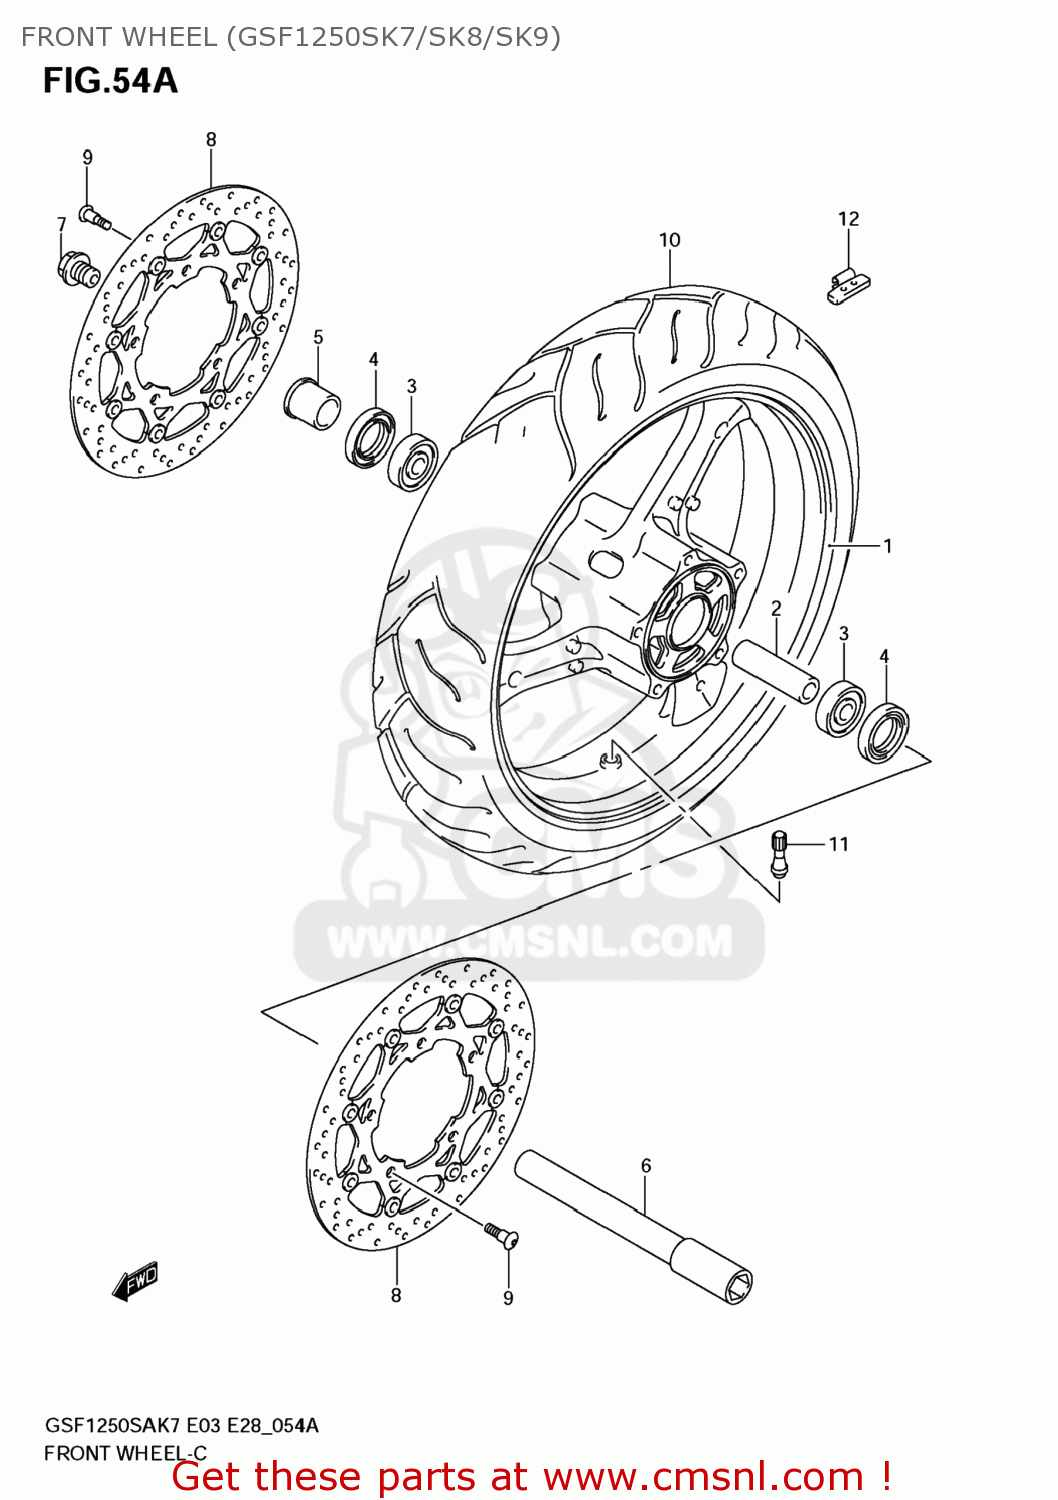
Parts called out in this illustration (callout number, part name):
1	WHEEL,FR(17M/CXMT3.50)
2	SPACER,FR HUB BEARING
3	BEARING(25X52X15)
4	SEAL,OIL(32X52X7)
5	SPACER,FR AXLE,R
6	AXLE,FR
7	BOLT,FRONT AXL
8	DISC,FRONT BRA
9	BOLT(8X21)
10	TIRE,FR
11	VALVE ASSY,WHEEL RIM(TR412)
12	BALANCER,WHEEL(10G)
